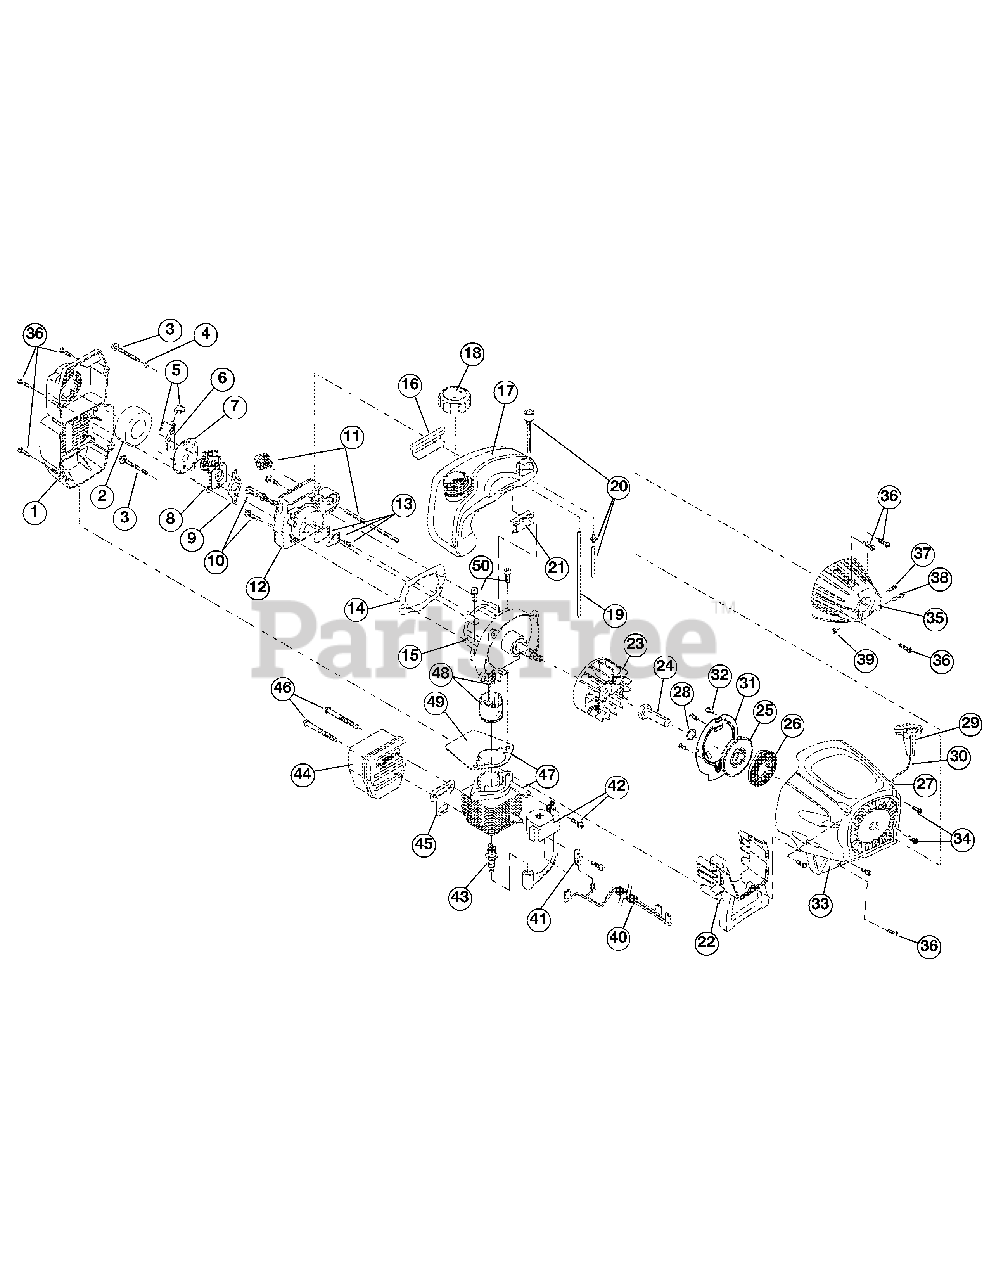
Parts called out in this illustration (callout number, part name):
1	Air Cleaner Cover Assembly (includes 2 & 37)
2	Air Cleaner Filter
3	Carburetor Mounting Screw Assembly
4	Wavey Washer
5	Choke Knob w/Screw
6	Choke Lever (includes 5)
7	Choke Plate (includes 6)
8	Carburetor Assembly (includes 9 & 20)
9	Carburetor Gasket
10	Carb Mount Screw
11	Primer & Hose Assembly
12	Carb Mount Assembly (includes 10, 13 & 14)
13	Reed Assembly
14	Carburetor Mount Gasket
15	Crankcase Service Assembly (includes 10)
16	Rear Mounting Pad
17	Fuel Tank Assembly (includes 18-20)
18	Fuel Cap Assembly
19	Fuel Return Line
20	Fuel Line Assembly
21	Front Mounting Pad
22	Shroud Extension & Stand (includes 39)
23	Flywheel Assembly
24	Square Nut Drive
25	Recoil Pulley Assembly (includes 26, 28 & 30)
26	Recoil Spring
27	Rope Guide
28	Pulley Retainer
29	Pull Handle
31	Pressure Plate Assembly (includes 32)
32	Plate Screw
33	Starter Housing Assembly (includes 25-32, 34 & 36)
34	Housing Screw
35	Clutch Cover Assembly (includes 36-39)
36	Cover Screw
37	Anti-Rotation Screw
38	Clamping Screw
39	Clamping Nut
40	Wire Leads and Sleeve
41	Ground Tab
42	Module Assembly
44	Muffler Assembly (includes 45, 46 & Spark Arrestor)
45	Exhaust Gasket
46	Muffler Mounting Bolts
47	Cylinder Assembly (includes 49 & 50)
48	Piston and Rod Assembly
49	Cylinder Gasket
50	Cylinder Bolt
